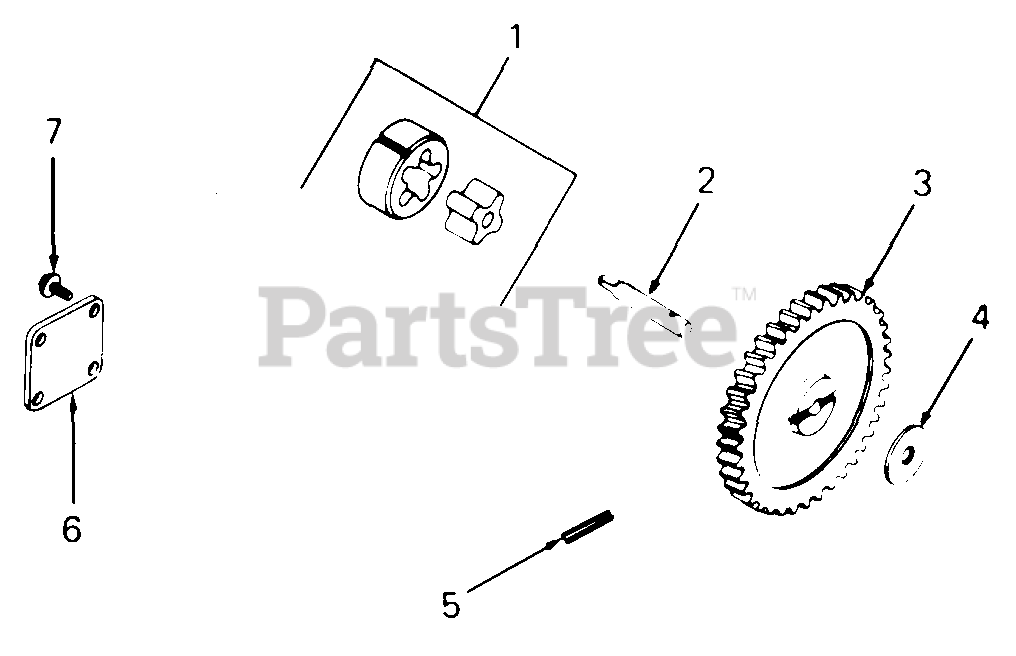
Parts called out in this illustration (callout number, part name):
2	Shaft, Oil Pump
3	Gear, Oil Pump
4	Spacer, Shim
6	Cover, Oil Pump
7	Screw, Hex Wash Hd, #10-32 x .43 Lg
